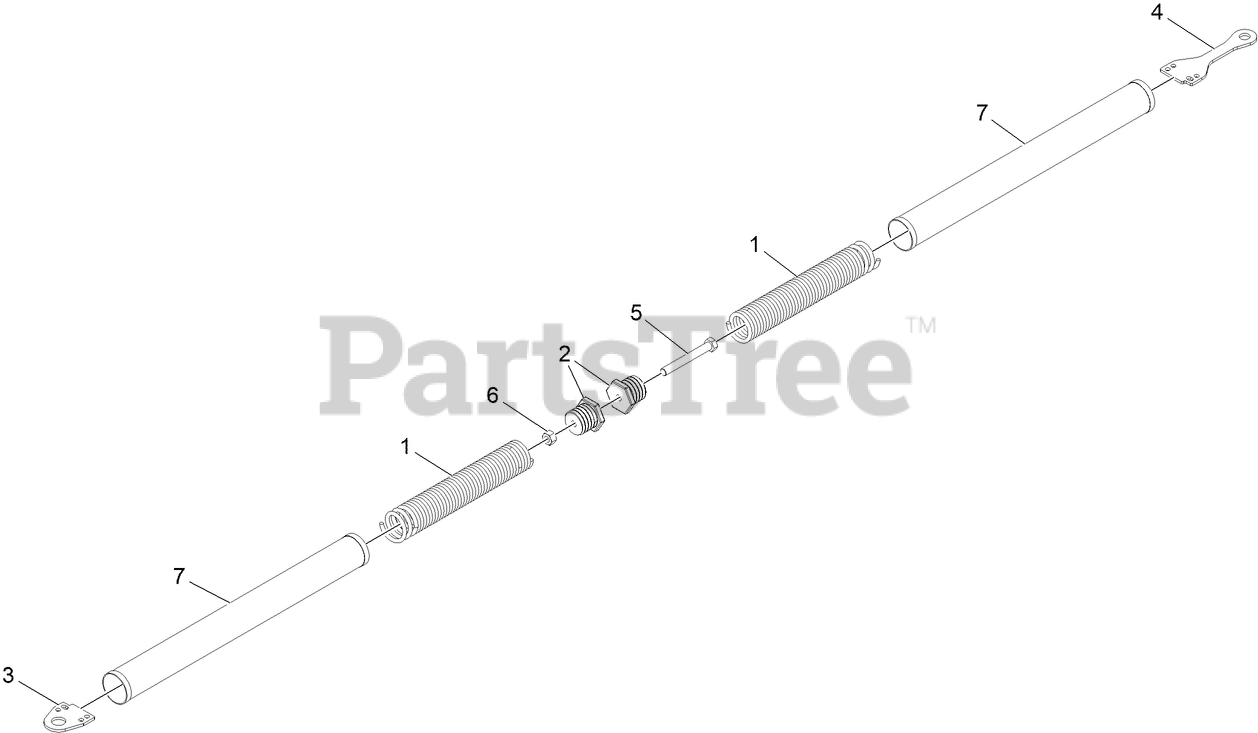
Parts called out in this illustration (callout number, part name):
1	SPRING-EXTENSION
2	PLUG-ADJUSTER, SPRING
3	PLATE-SPRING EYE
4	SPRING-TAB
5	BOLT-TAP
6	NUT-HH
7	COVER-SPRING, DECK
